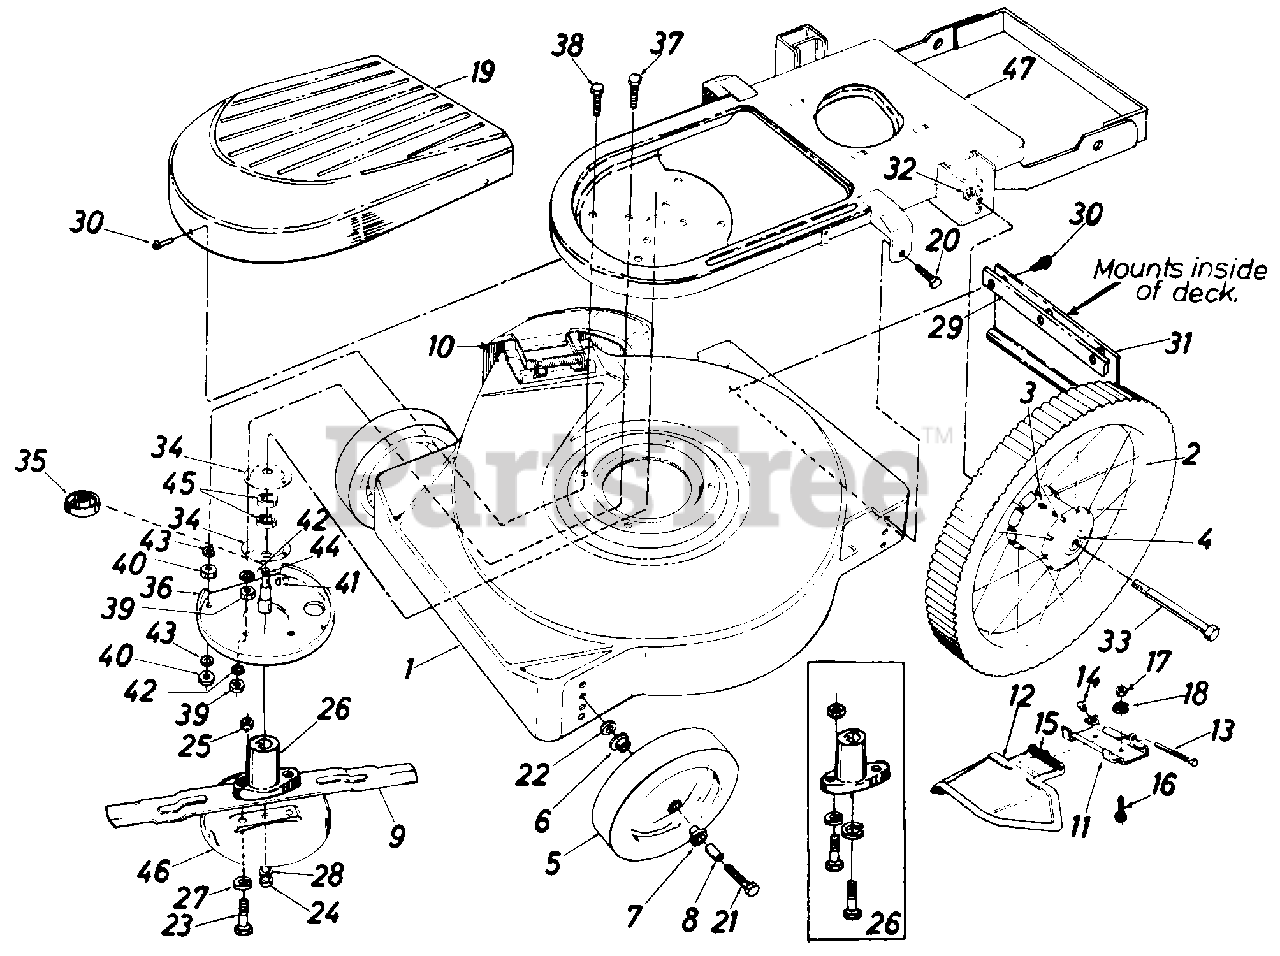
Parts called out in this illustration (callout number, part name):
3	Oil Cap
4	Ball Bearing
5	Wheel Ass'y. Comp. 8"
6	Flanged Ball Bearing 3/8" I.D.
7	Flanged Ball Bearing 1/2" I.D.
8	Spacer
9	22" Blade
10	Chute Deflector Ass'y. Comp.
11	Adapter Plate
12	Deflector Ass'y.
13	Pivot Pin
14	Push Cap 1/4" Rod
15	Torsion Spring
16	Hex Bolt 1/4-20 x .50" Lg.
17	Hex Nut 1/4-20 Thd.
18	L-Wash. 1/4" I.D.
19	Blade Spindle Cover
20	Hex Sems Scr. 3/8-16 x .62"
21	Hex Bolt 3/8-16 x 2.0" Lg.
22	Bell-Wash. .400" I.D. x .88"
23	Hex Bolt 5/16-24 x 1.00" Lg.
24	Hex Bolt 3/8-24 x 2.25" Lg.
25	Hex Nut 5/16-24 Thd.
26	Blade Adapter Kit
27	L-Wash. 5/16" I.D.
28	L-Wash. 3/8" I.D. H.D.
29	Retaining Strip
30	Hex Wash. Hd. AB-Tap Scr. 1/4" x .62" Lg.
31	Rear Flap Ass'y.
32	Bell-Wash. .400" I.D. x .88"
33	Rear Axle Bolt
34	Bearing Housing
35	Bearing Shield
36	Blade Reinforcement Plate
37	Hex Bolt 5/16-24 x 1.25" Lg.
38	Hex Bolt 3/8-24 x 1.25" Lg.
39	Hex Nut 5/16-24 Thd.
40	Hex Nut 3/8-24 Thd.
41	#6 Hi-Pro Key 5/32" x 5/8" Dia.
42	L-Wash. 5/16" I.D.
43	L-Wash. 3/8 I.D.
44	Blade Spindle
